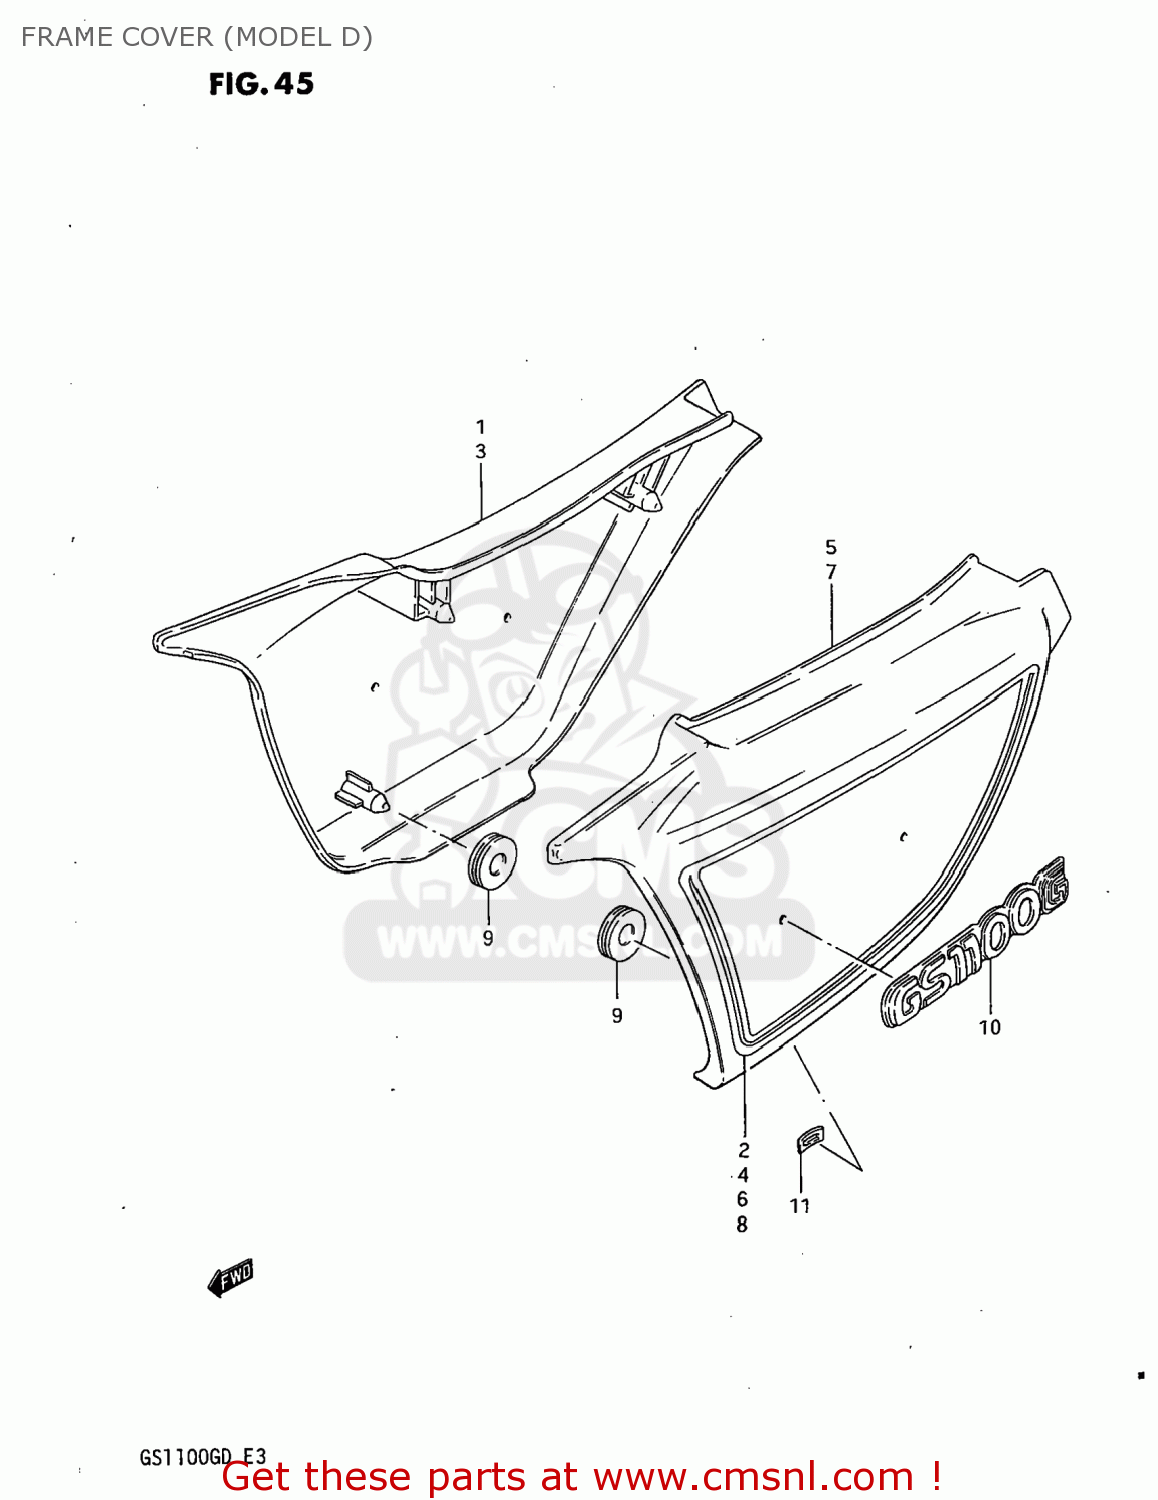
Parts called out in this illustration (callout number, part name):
1	COVER,FRAME,RIGHT
2	TAPE SET,FRAME COVER
3	COVER,FRAME,RIGHT
4	TAPE SET,FRAME COVER
5	COVER,FRAME,LEFT
6	TAPE SET,FRAME COVER
7	COVER,FRAME,LEFT
8	TAPE SET,FRAME COVER
9	CUSHION
10	EMBLEM
11	NUT
